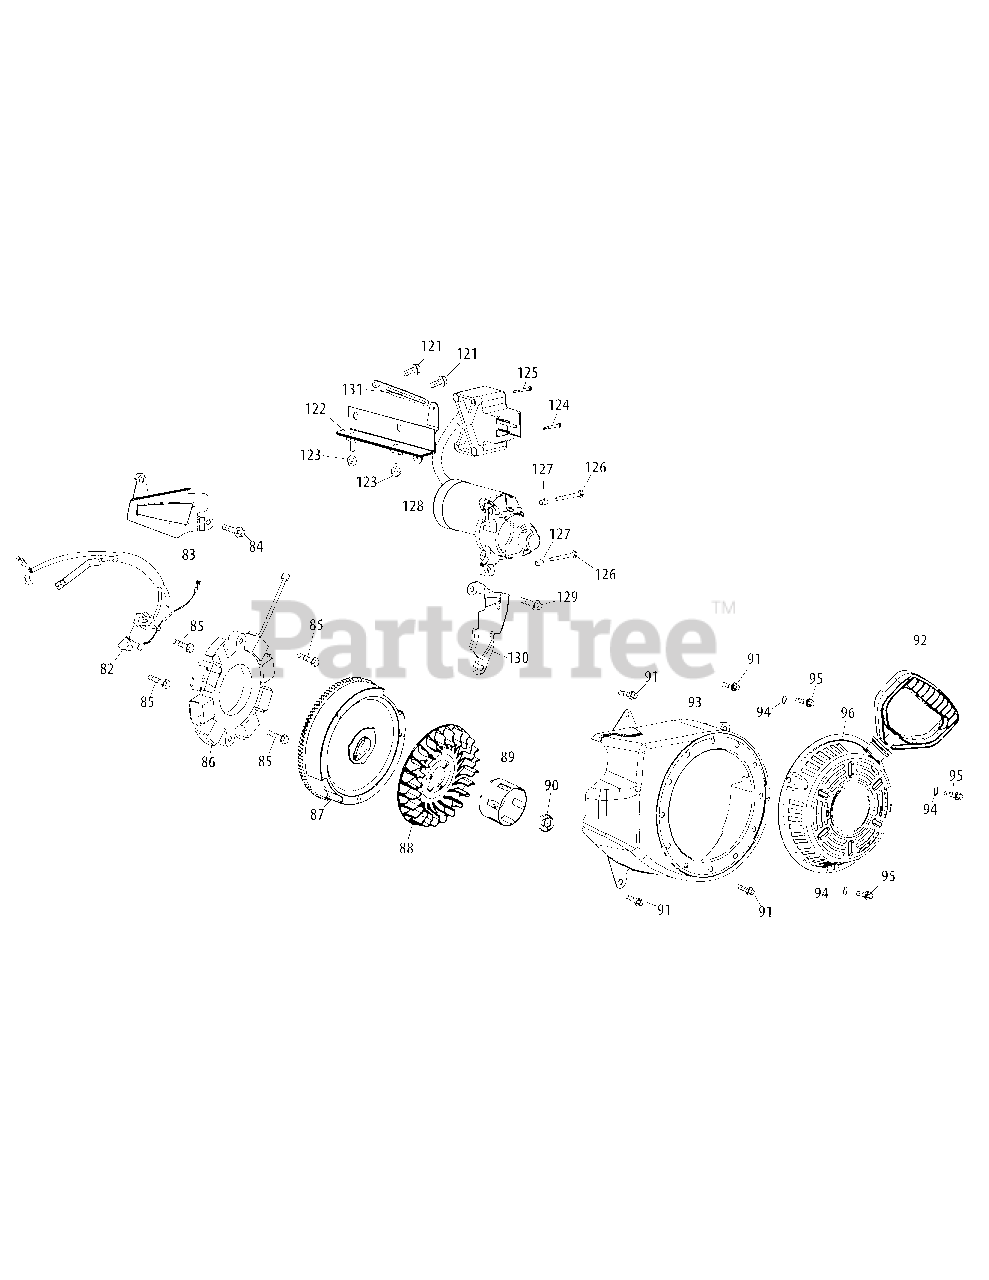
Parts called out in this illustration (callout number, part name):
82	Ignition Coil Assembly
83	Air Flow Shield
84	Bolt M6×10
85	Bolt M6×25
86	Coil Assy., Charge
87	Flywheel
88	Fan,Cooling
89	Pulley, Starter
90	Nut, Special,M14×1.5
91	Bolt M6×12
92	Recoil Starter Handle
93	Blower Housing
94	Gasket 6
95	Bolt M6×10
96	Recoil Starter
121	Bolt M6×10
122	Switch Housing Mounting Bracket
123	Nut, M6
124	Bolt M4×55
125	Bolt M4×60
126	Bolt M6×32
127	Dowel Pin 8×8
128	Electric Starter
129	Bolt M6×18
130	Blower Housing Shield
131	Flexible Clamp
